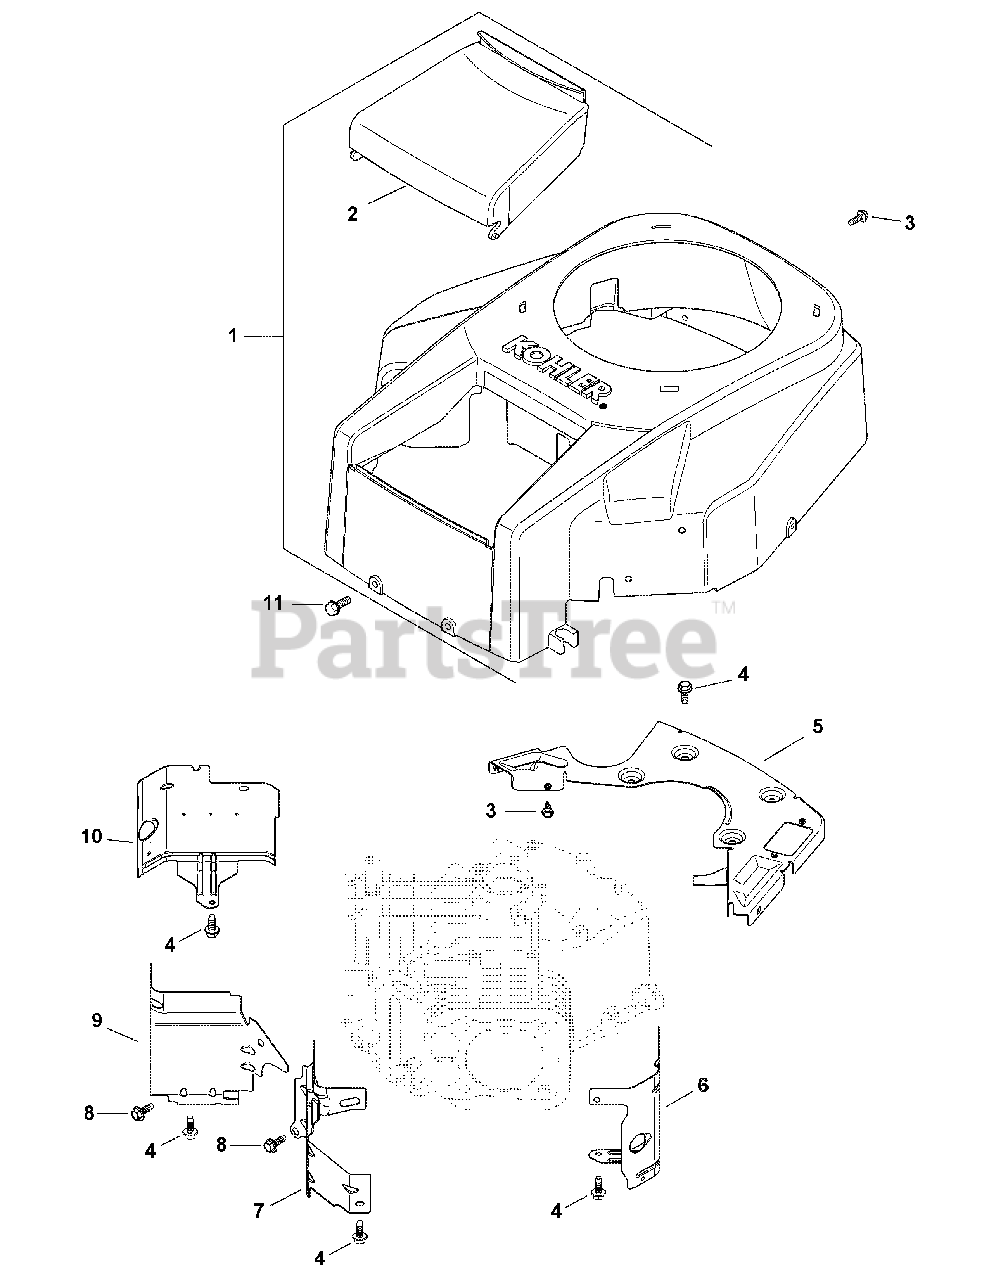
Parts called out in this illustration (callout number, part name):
1	Kit, Blower Hsng
2	Cover, Air Cleaner
3	Screw, Flnge Thrd. Frmng M5 x 0.8x 16
4	Screw, Flnge Thrd. Frmng M6 x 1.0 x 16
5	Plate, Backing
6	Baffle, Cyl. Barrel - #2 Side
7	Baffle, Valley #2 Side
8	Screw, Flnge Thrd. Frmng M5 x 0.8x 10
9	Baffle, Valley #1 Side
10	Baffle, Cylinder Barrel - #1 Side
11	Screw, Tap, M6 x 1.7 x 18
